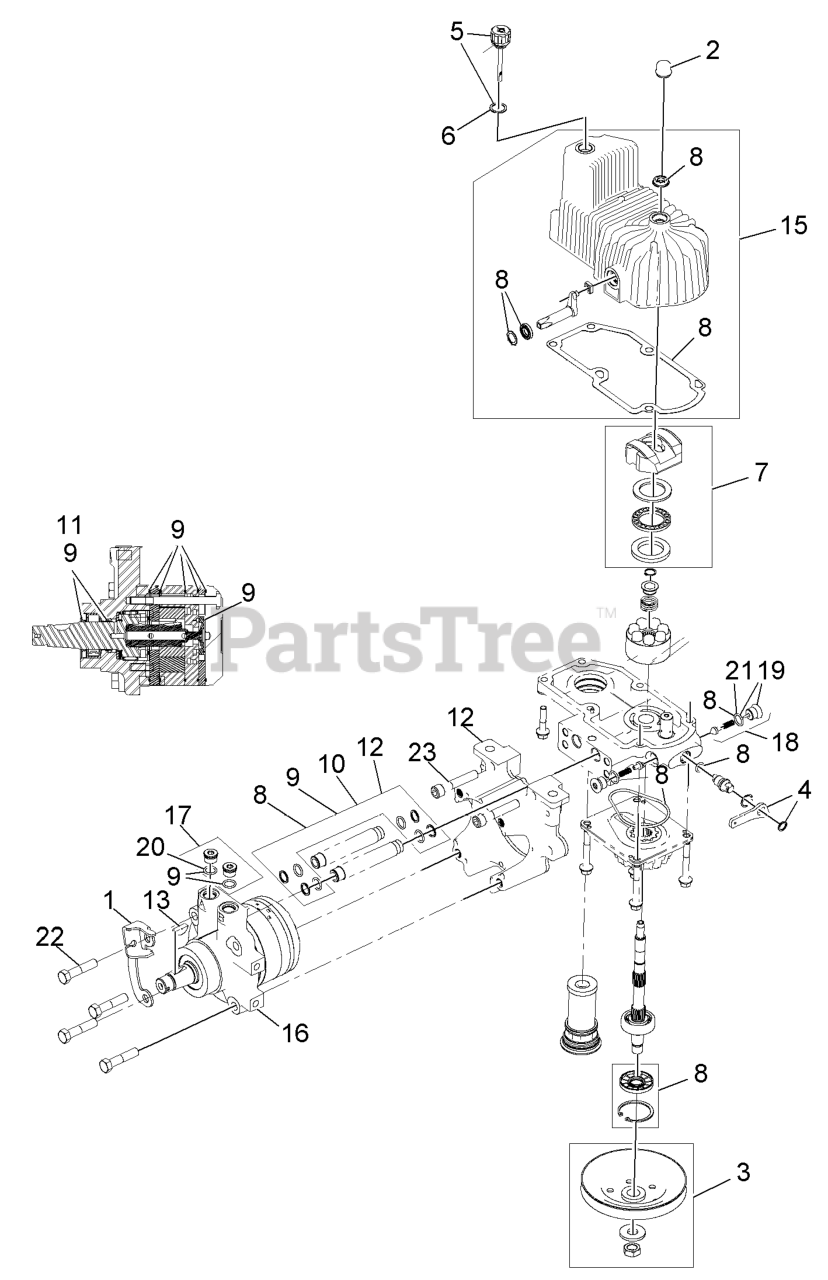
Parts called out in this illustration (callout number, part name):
1	BRACKET-ANCHOR, CABLE
2	COVER-SHAFT, HYDRO
3	PULLEY KIT
4	HANDLE-BYPASS VALVE, HYDRO
5	DIPSTICK-HYDRO W/GASKET
6	GASKET-DIPSTICK, HYDRO
7	SWASH BLOCK KIT
8	PUMP SEAL KIT
9	MOTOR SEAL KIT
10	TUBE SEAL KIT
11	OUTPUT SHAFT SEAL KIT
12	NOSE CUP-UHT
13	KEY-WOODRUFF
15	HOUSING-HYDRO, LH
16	MOTOR-HYDRAULIC LH 240CC
17	MAGNETIC PLUGS SERVICE KIT
18	CHECK VALVE ASM
19	PLUG-CHECK (W/O-RING)
21	O-RING-CHECK VALVE
22	SCREW HH
23	SCREW-HSH
